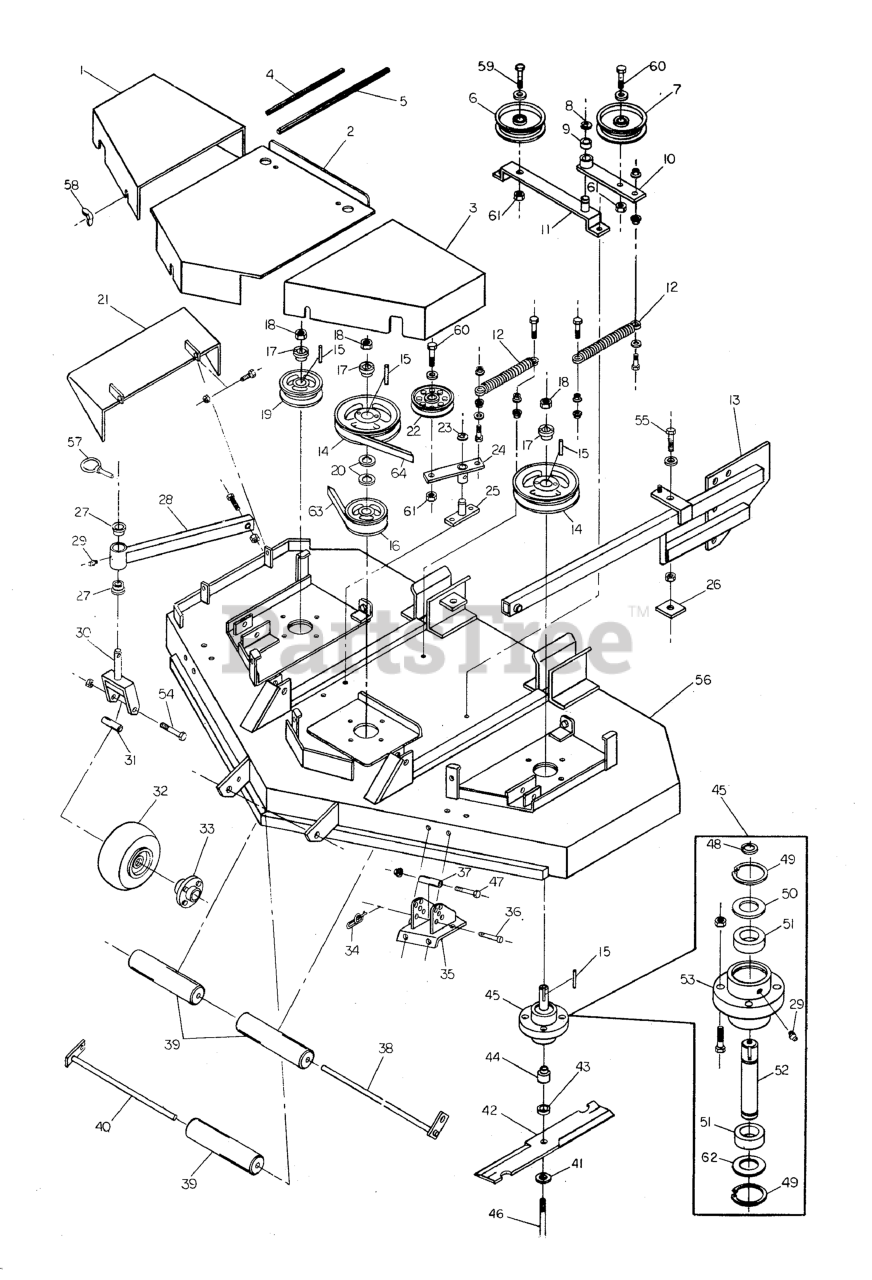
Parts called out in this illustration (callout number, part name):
1	Guard Right Side
2	Center Guard
3	Guard Left Side
4	Body Molding 17 5/8" Long
5	Body Molding 24" Long
6	PULLEY, Backside Idler
7	Idler Pulley
8	C-CLIP
9	BELT, Blade Spindle
10	IDLER ARM, Complete
11	Idler Mount
12	SPRING, Extension
13	Deck Mounting Arm left
13	Deck Mounting Arm Right
14	PULLEY, Spindle
15	KEY, 1/4 SQ. X 2-1/2
16	SPINDLE PULLEY
17	BUSHING, Tapered Hub
18	NUT, 5/8-11 Hex
19	PULLEY, Spindle
20	1/8" Spacer
21	DISCHARGE CHUTE
22	Idler Pulley
23	C-CLIP
24	Idler Arm
25	IDLER MOUNT
26	Weld Nut
27	Plastic Bushing
28	Caster Arm
29	GREASE FITTING
30	Caster Yoke
31	AXLE, Caster Wheel
32	WHEEL & TIRE ASSEMBLY, White, 9 x 3.5 x 4, Complete
34	Rue Clip
35	Caster Guide Left
35	Caster Guide Right
36	3/8 Clevis Pins
37	SPACER, .38 x .50 x 1.50
38	Roller Support Rod
39	Drive Tire Assembly (Tire & Rim)
41	WASHER, 5/8" USS
42	MOWER BLADE, 24-1/2"
43	SPACER, .64 x 1.75 x .25
44	Spindle Spacer
45	Spindle Assembly
46	BOLT, 5/8-11 x 9-1/2
47	BOLT, 3/8-16 X 2-1/2" GD5 CZ
48	SNAP RING, External
49	SNAP RING, Internal
50	SPINDLE WASHER, Top
51	BEARING
52	SPINDLE SHAFT
53	SPINDLE HOUSING
54	BOLT, 1/2-13 x 5-1/2
55	1/2-13 x 5-1/2 Bolt
56	72" MOWER HOUSING
57	PIN, Lynch
58	NUT, 3/8-16 Wing Nylon Lock
59	BOLT, 1/2-20 X 2-1/2" GD5 CZ
60	BOLT, 1/2-20 X 2-1/4 GD5 CZ
61	NUT, Hex, Nylon Lock, 1/2-20
62	SPINDLE WASHER, Bottom
